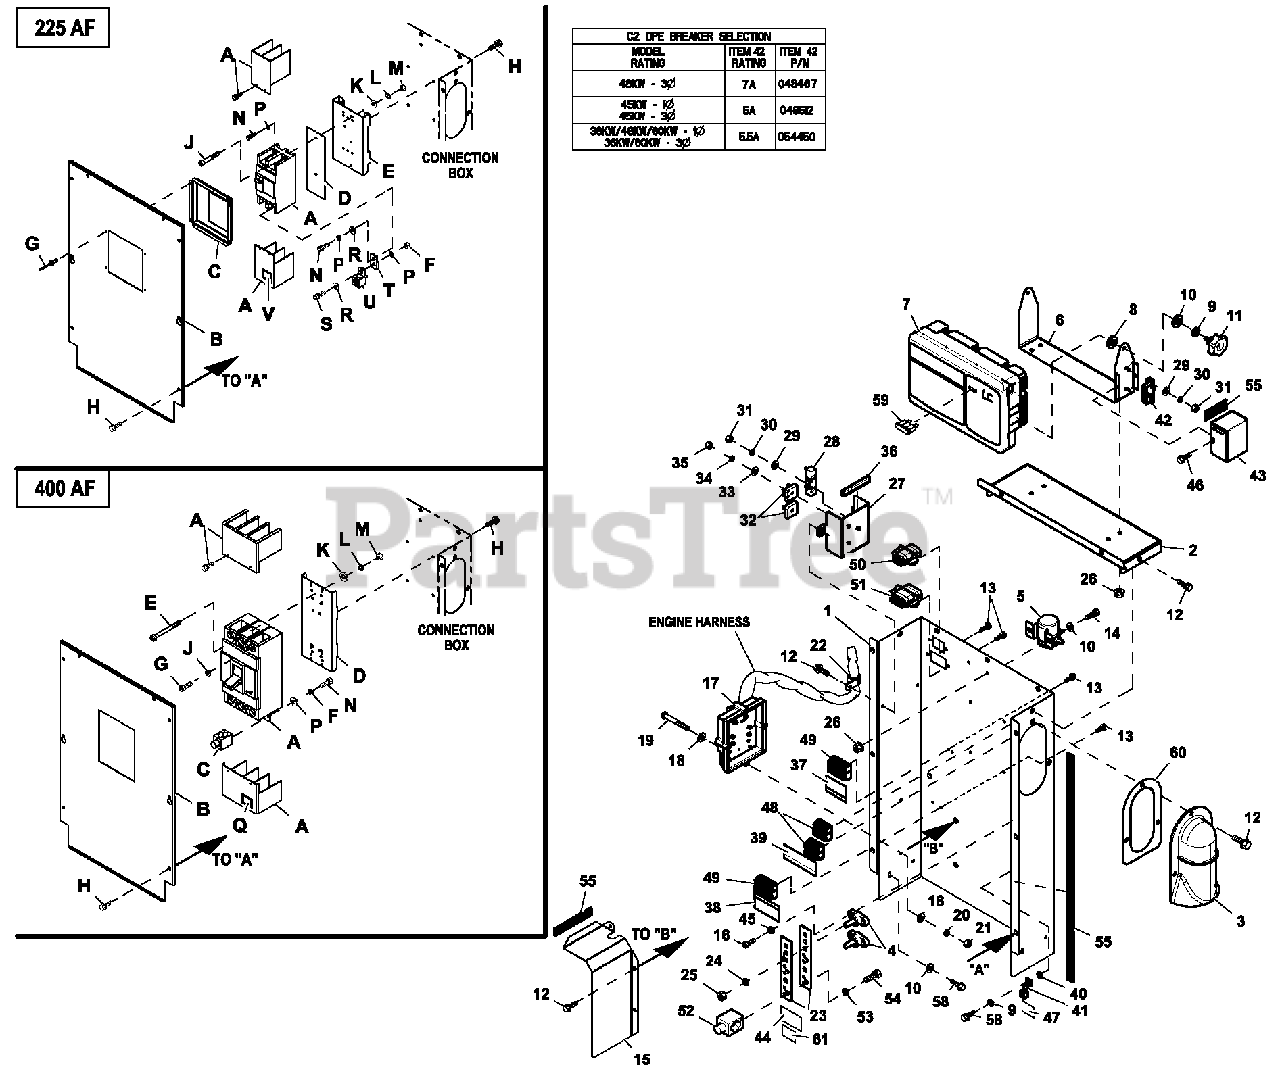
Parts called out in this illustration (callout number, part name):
1	BACK PANEL CONBOX SUPPORT C2
2	TOP PANEL CONBOX SUPPORT C2
3	COVER WIRE ENTRY CONBOX
4	JUNCTION BLOCK 3/8-16
5	RELAY SOLENOID 12VDC PNL MNT
6	BRACKET GIMBAL CONTROL PNL RAW
7	ASSY CTRL PROGRAMMED
8	WASHER FLAT NYLON 0.257 X 0.625
9	WASHER LOCK M6-1/4
10	WASHER FLAT 1/4-M6 ZINC
11	KNOB M6-1.0 CONTROL PANEL
12	SCREW HWHT M6-1 X 16 N WA Z/JS
13	SCREW HHSP #10 X 3/8 HI-LOW
14	SCREW HHC M6- 1.0 X 20 C8.8
15	SHIELD HIGH/LOW C2 RAW
16	SCREW PHTT M4-0.7 X 12 ZP
17	ASSY PROG 2010 IGN MOD 6 CYL
18	WASHER FLAT #10 ZINC
19	SCREW PPHM #10-32X2
20	WASHER LOCK #10
21	NUT HEX #10-32 STEEL
22	CLAMP STL/VNL 1.06 X .406 Z
23	NEUTRAL BLOCK 390/200-400A
24	WASHER LOCK 3/8
25	NUT HEX 3/8-16 STEEL
26	NUT FLANGE M6-1.0 NYLOK
27	COVER VOLTAGE SHIELD
28	RES WW 15R 5% 25W QK CONN
29	WASHER FLAT M3
30	WASHER LOCK M3
31	NUT HEX M3-0.5 G8 CLEAR ZINC
32	DIODE BRIDGE 1P 35A 1000V
33	WASHER FLAT M5
34	WASHER LOCK M5
35	NUT HEX M5-0.8 G8 CLEAR ZINC
36	TRIM VINYL BLACK 1/8GP (3"LG)
37	DECAL CUSTOMER POWER CONNECT
38	DECAL CUSTOMER CONTROL CONNECT
39	DECAL CONBOX TB1 CONNECTIONS
40	WASHER LOCK EXT 1/4 STL
41	LUG SLDLSS #2-#8 X 17/64 CU
42	CIRCUIT BREAKER
43	COVER DPE BREAKER NEXUS RAW
44	DECAL NEUTRAL
45	WASHER LOCK#8-M4
46	SCREW HHTT M4-0.7 X 8 ZP
47	DECAL GROUND LUG
48	TERM BLOCK 3P UL 12-20AWG
49	TERM BLOCK 4P UL 12-20AWG
50	MX150L SLRRMNT 22-18 8P W/O GA
51	MX150L SLRRMNT 22- 18 12P W/OGA
52	LUG SLDLSS 600/250-1/0X1/4-28
53	WASHER LOCK 1/4- M6 SS
54	SCREW HHC 1/4-28 X 3/4 G5
55	TAPE ELEC 1/2 FOAM (69"LG)
58	SCREW HHTT M6-1.0 X 16 ZYC
59	FUSE ATO TYPE 7.5AMP (BROWN)
60	GASKET WIRE ENTRY COVER
61	DECAL CAUTION ELEC SHOCK SM
A	CB 175A 2 POLE 240V 225AF
B	COVER CB C2 CPL
C	COVER CB DISH 2P G 225AF
D	INSULATOR CB 2P 225AF
E	STANDOFF CB BOX CONBOX
F	NUT HEX M8-1.25 G8 CLEAR ZINC
G	RIVET POP .125 X .275 SS
H	SCREW HWHT M6-1 X 16 N WA Z/JS
J	SCREW RHM #8-32X3-1/4
K	WASHER FLAT #8 ZINC
L	WASHER LOCK#8-M4
M	NUT HEX #8-32 STEEL
N	SCREW SHC M8-1.25 X 20 G8
P	WASHER LOCK M8-5/16
R	WASHER FLAT 5/16-M8 ZINC
S	SCREW SHC M8-1.25 X 25 C12.9
T	BUS BAR 200A LUG ADAPTOR
U	LUG SLDLSS 300 MCM-6 AL/CU
V	DECAL TERMINAL SHOCK HZD BI
A	CB 0250A 3P 480V G 400AF
B	COVER CB 400AF C2 CONBOX
C	LUG SLDLSS 600/250-1/0X1/4-28
D	STANDOFF CB MOUNT CONBOX
E	SCREW RHM 10-32X4
F	WASHER LOCK M6-1/4
G	SCREW SHC M10-1.5 X 25 C12.9
J	WASHER LOCKM10
K	WASHER FLAT #10 ZINC
L	WASHER LOCK #10
M	NUT HEX #10-32 STEEL
N	SCREW HHC 1/4-28 X 1/2 G5
P	WASHER FLAT 1/4-M6 ZINC
Q	DECAL TERMINAL SHOCK HZD BI
